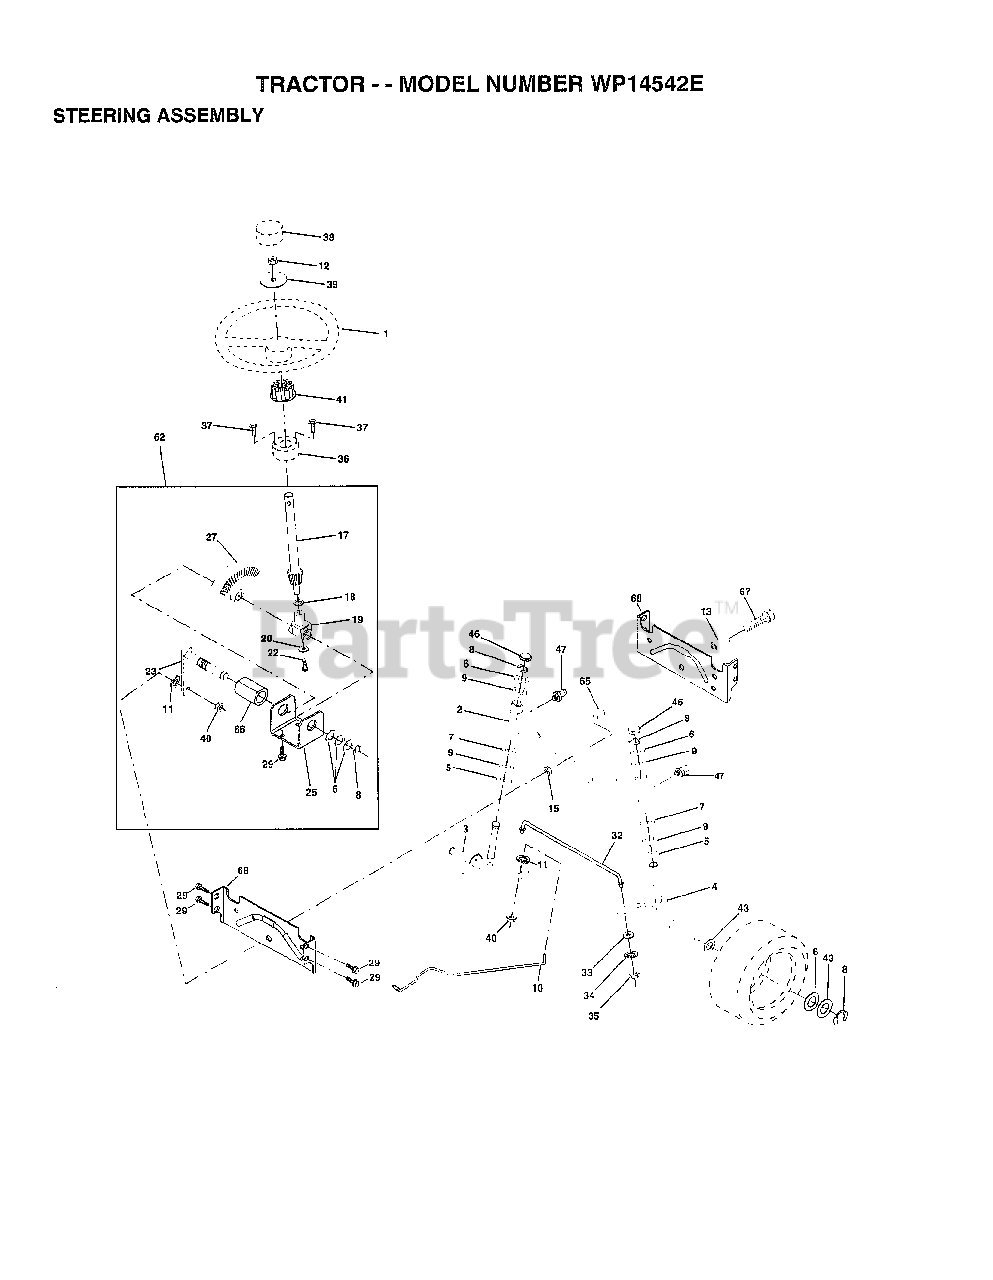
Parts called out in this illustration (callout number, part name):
2	AXLE ASM
3	SPINDLE.ASM.LH
4	"SPINDLE ASM,RH"
5	WASHER .T
6	WASHER
7	WASHER
8	RING
9	COL. SRTG. BEAR.
10	DRAGLINK-STAMPED
11	LOCKWASHER
13	BEARING AXLE
15	"NUT-LOC,FLANGE LT"
17	SHAFT ASM STEERNG
18	THRUST WASHER
19	SUPPORT.SHAFT
22	SCREW HEX SOC1/4-
25	BRKT-STEERING
27	GEAR SECTOR
29	SCREW
32	ROD.TIE.19.75
33	WASHER M
34	LOCKWASHER
35	NUT.LOCK.5/16-24
36	BUSHING.STRG.3/4
37	"SCREW-TT,10-32 FL"
38	"INSERT,STR WHEEL"
39	WASHER
40	GRIPCO NUT
41	ADAPTER LT
46	CAP
47	ZERK M
62	KIT STEERING ASM
65	SPACER AXLE
66	"BEARING-ARM,PITMA"
67	BOLT
68	BRACE AXLE
